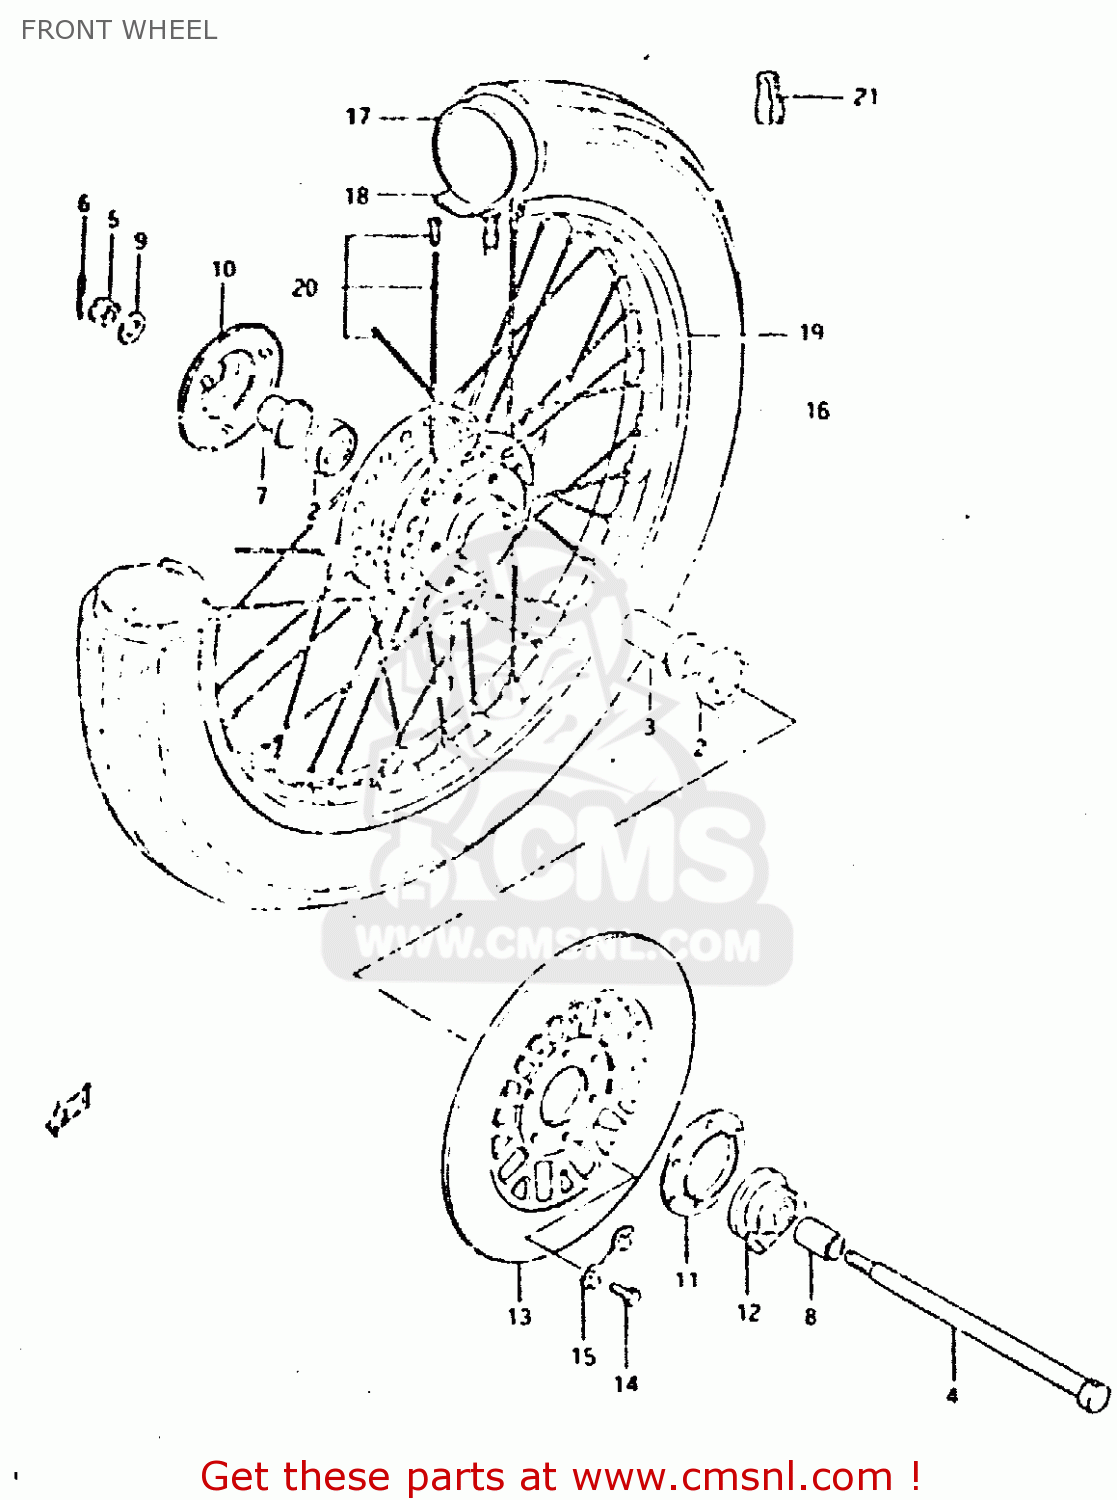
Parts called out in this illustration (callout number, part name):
1	DRUM,FRONT HUB
2	BEARING
3	SPACER,FR HUB BEARING
4	AXLE,FRONT
5	NUT 12MM
6	COTTER PIN
7	SPACER,FR HUB BEARING,R
8	SPACER(15X22X30)
9	WASHER
10	COVER,FR HUB,R
11	DUST SEAL,SPEEDOMETER GEAR BOX
12	BOX ASSEMBLY,SPEEDOMETER GEAR
13	DISC,FR BRAKE
14	BOLT(8X25)
15	WASHER
16	TIRE
17	TUBE 2.75-19 070-483MM
18	PROTECTOR,WHL INR TUBE
19	RIM,FR WHEEL
20	SPOKE ASSY,FR
21	BALANCER,WHEEL (B)
